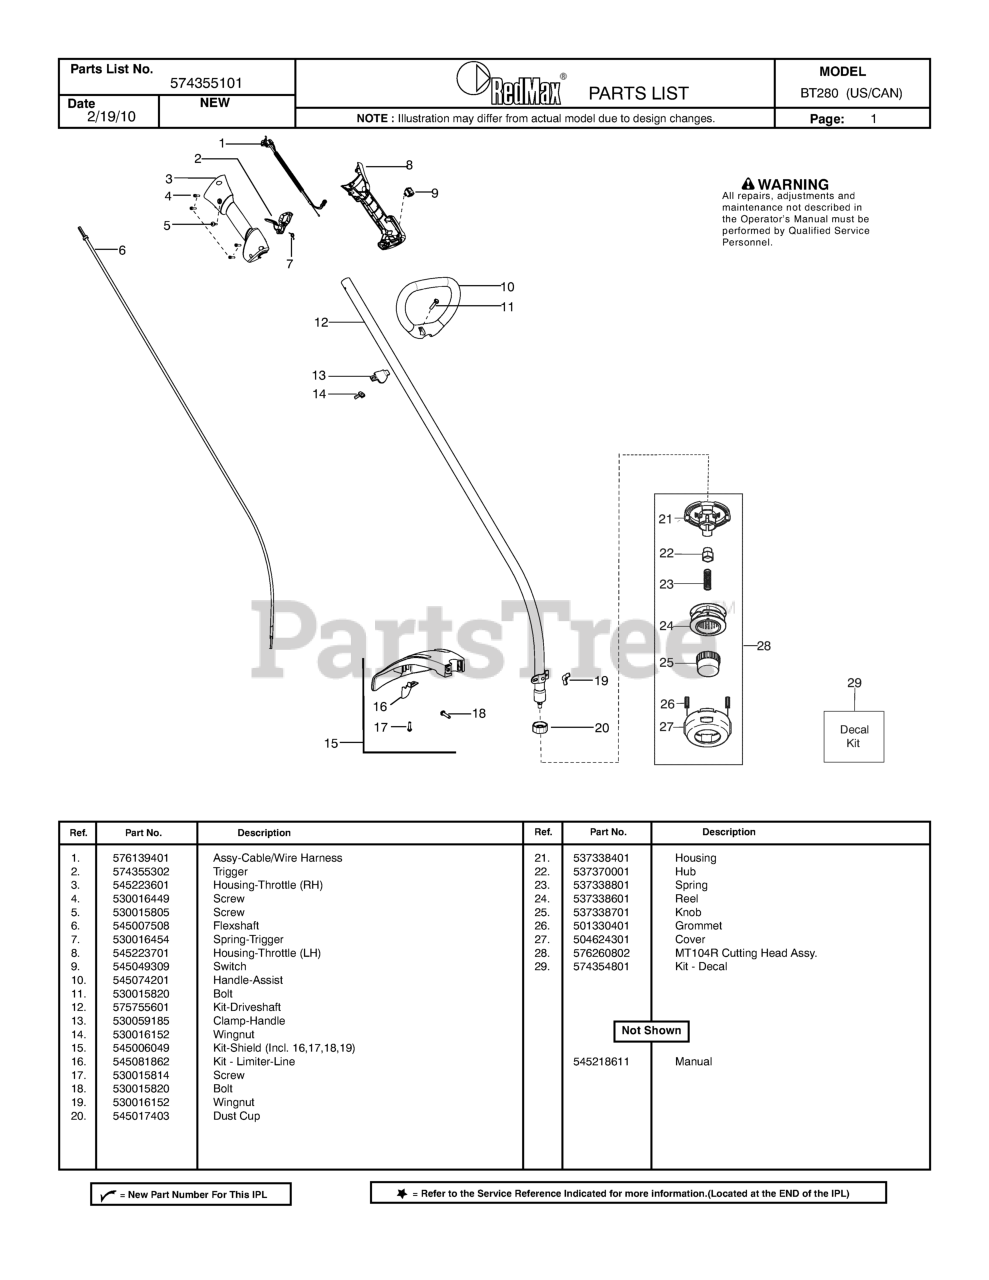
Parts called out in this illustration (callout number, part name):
1	ASSY CABLE/WIRE HARNESS
3	HOUSING-THROTTLE
5	SCREW
6	FLEXSHAFT
7	SPRING-TRIGGER
8	HOUSING-THROTTLE LH
10	HANDLE ASSIST
12	KIT DRIVESHAFT
13	CLAMP HANDLE
14	WINGNUT
15	KIT SHIELD
16	KIT LIMITER LINE
19	WINGNUT
20	DUST CAP
28	MT104R CUTTING HEAD ASSY
29	KIT DECAL
